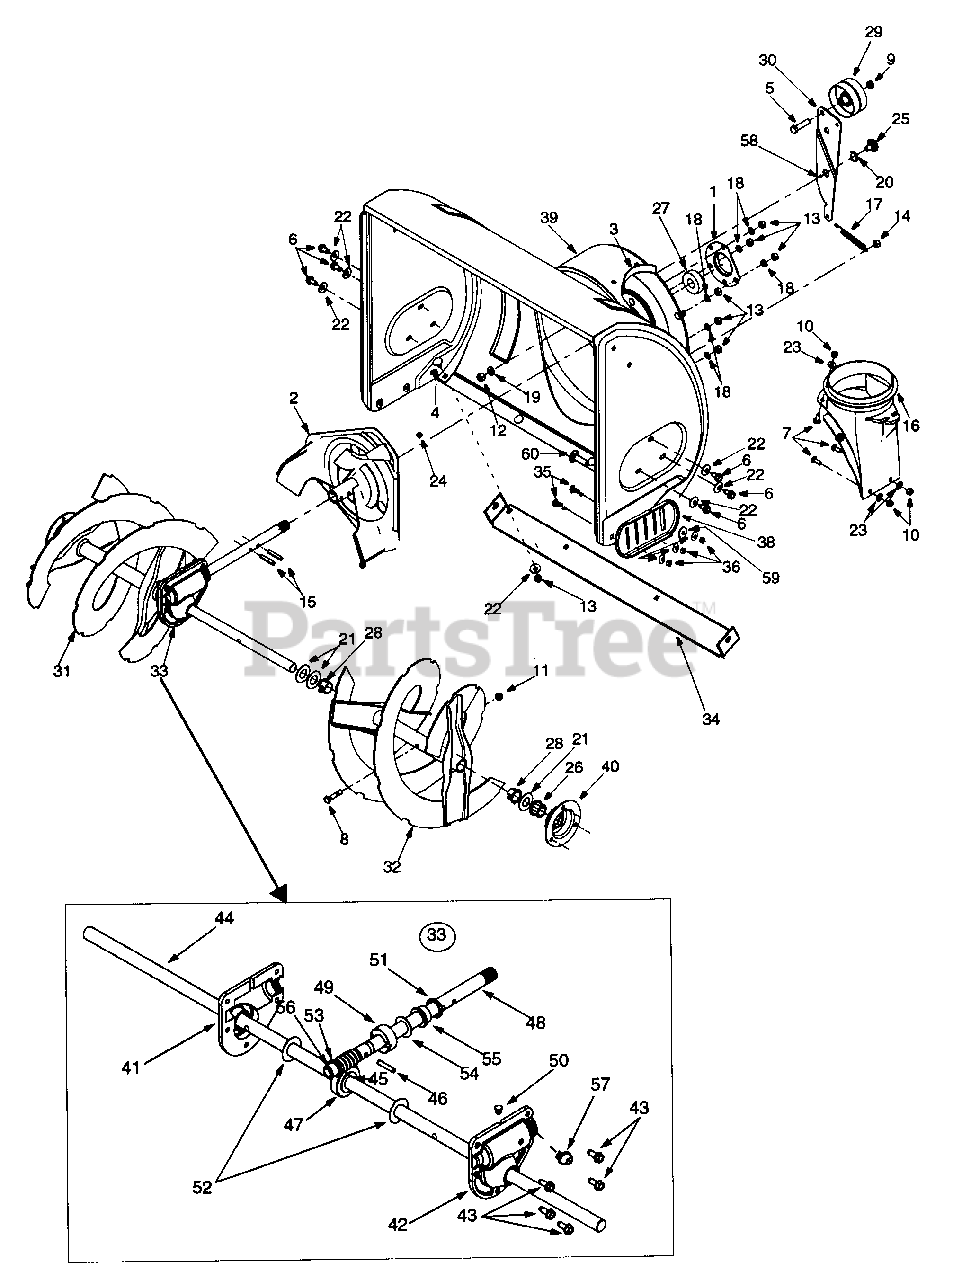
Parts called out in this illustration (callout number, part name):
1	Bearing Housing
4	Carriage Bolt 5/16-18 x .75" Gr.2
5	Hex Screw 3/8-24 x 1.5" Gr.5
6	Hex Washer Head Self-Tapping Screw 5/16-18 x .62"
7	Carriage Screw 1/4-20 x .75"
8	Shear Bolt 5/16-18 x 1.5"
9	Jam Nut 3/8-24
10	Hex Lock Nut 1/4-20
11	Hex Lock Nut 5/16-18
12	Hex Nut 3/8-16 Gr.2
13	Hex Nut 5/16-18 Gr.5
14	Hex Patch Nut 5/16-18
16	Chute Adapter
17	Extension Spring
18	Lock Washer
22	Belleville Washer
24	Grease
25	Shoulder Screw
26	Hex Flange Bearing
27	Flange Ball Bearing
28	Flange Bushing
31	Spiral Assembly: RH 26"
32	Spiral Assembly: LH 26"
33	Gear Assembly: Auger 26"
35	Carr. Bolt: 5/16-18 x 0.75
36	Hex Nut: 5/16-18 Gr.5
39	Auger Housing Assy. 26"
41	RH Housing
42	LH Housing
43	TT Screw, 1/4-20 x .75
44	Spiral Axle, 26"
45	Hi-Pro Key, 3/1 6 x 5/8
46	Spring Spiral Pin, .25 x 1.25
47	Worm Gear, 20T
48	Worm Shaft
49	Thrust Collar
52	Flat Washer, .76 x 1.5 x .030
53	Flat Washer, .508 x 1.0 x .020
54	Flat Washer, .76 x 1.5 x .060
55	Flange Bearing, .75 x 1.0 x .59
56	Flange Bearing, .503 ID x .75 OD
57	Grease Fitting
58	Alvania Grease (2 Ounces)
60	Carriage Screw: Special
